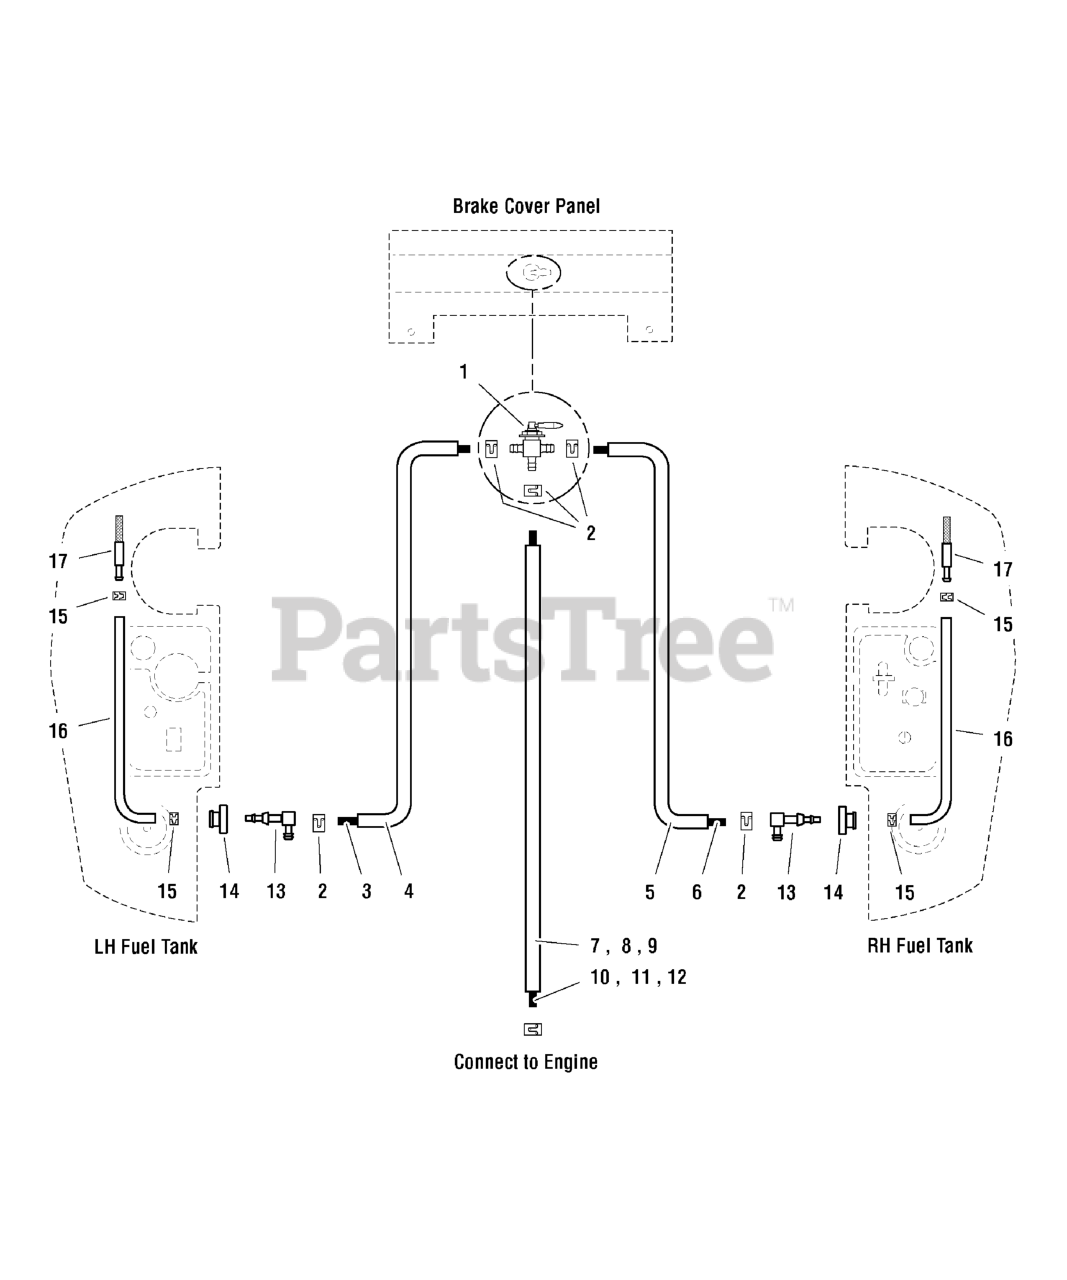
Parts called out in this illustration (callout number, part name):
1	VALVE, Fuel Shut Off
2	CLAMP, Hose
3	1/4" Fuel Line, 51" Long
4	WIRE LOOM, 48"
5	WIRE LOOM, 39"
6	1/4" Fuel Line, 41" Long
7	WIRE LOOM, 34"
8	WIRE LOOM, 43"
9	WIRE LOOM, 28"
10	1/4" Fuel Line, 36" Long
11	1/4" Fuel Line, 45" Long
12	1/4" Fuel Line, 30" Long
13	ELBOW FITTING
14	BUSHING-FUEL TANK RED RUBBER
15	SEE HOSE ASSEMBLY
16	ASSM, FUEL HOSE, 20"
17	SEE HOSE ASSEMBLY
